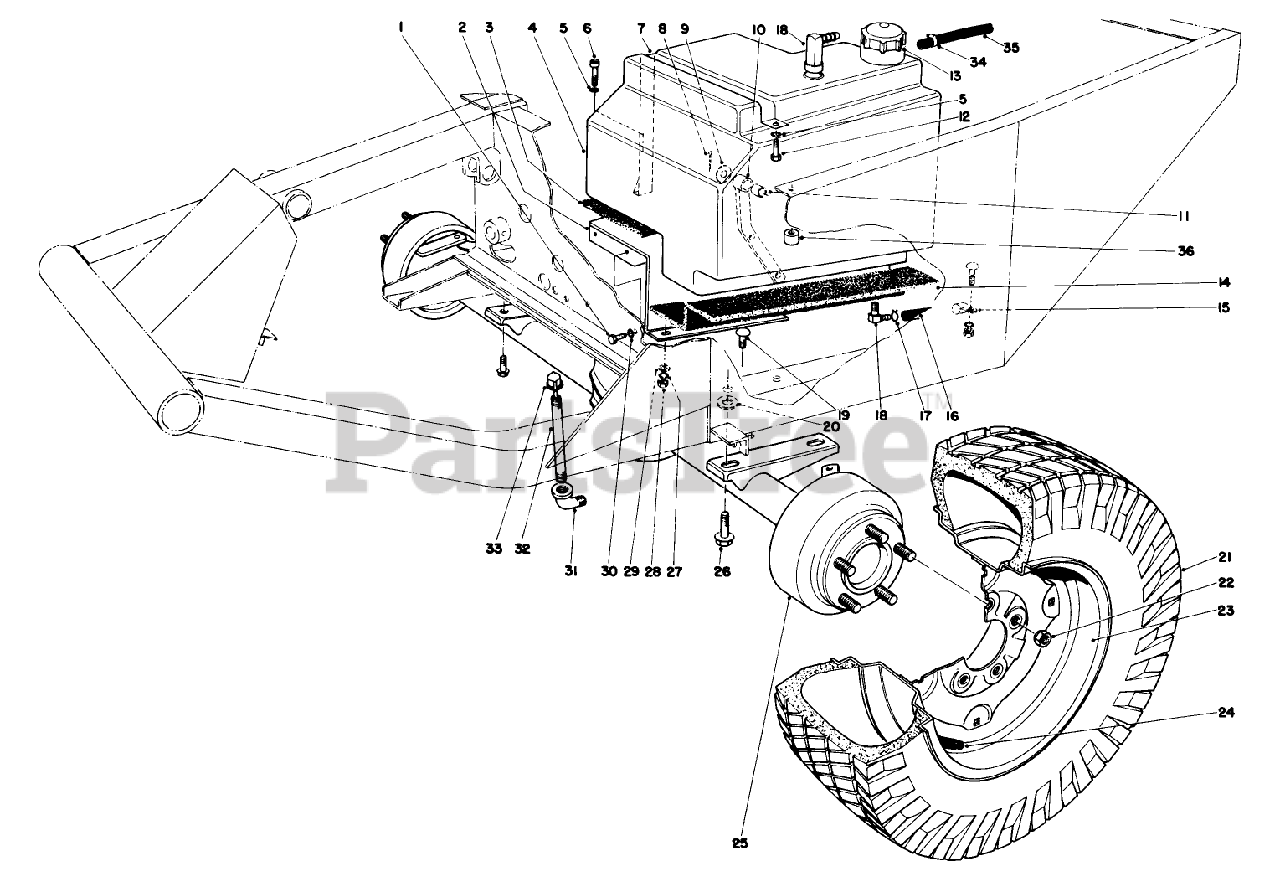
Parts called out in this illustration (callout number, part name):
1	SCREW-HH
2	GAS TANK BASE WA
3	FOAM-SUPPORT, TANK
4	Gas Tank (Incl. Ref. 18)
5	WASHER-LOCK
6	SCREW-HSH
7	STRAP-TANK, FUEL
8	PIN-COTTER
9	WASHER-THRUST
10	Steering Link (Incl. Ref. #11)
11	BUSHING
12	SCREW-HH
13	Gas Cap
14	FOAM-SUPPORT, TANK
15	CLAMP-R
16	HOSE-FUEL
17	CLAMP-HOSE
18	FITTING-ELBOW, 90 DEG
19	BOLT-CARR
20	SPECIAL WASHER
22	NUT-LUG
24	STEM-VALVE
25	Axle
26	SCREW-HHF
27	WASHER-LOCK
28	NUT-HEX
29	WASHER-PLAIN
30	WASHER-LOCK
31	FITTING-ELBOW-90
32	NIPPLE-PIPE
33	DIPSTICK ASM
34	CLAMP-HOSE
35	HOSE-FUEL
36	SPACER
